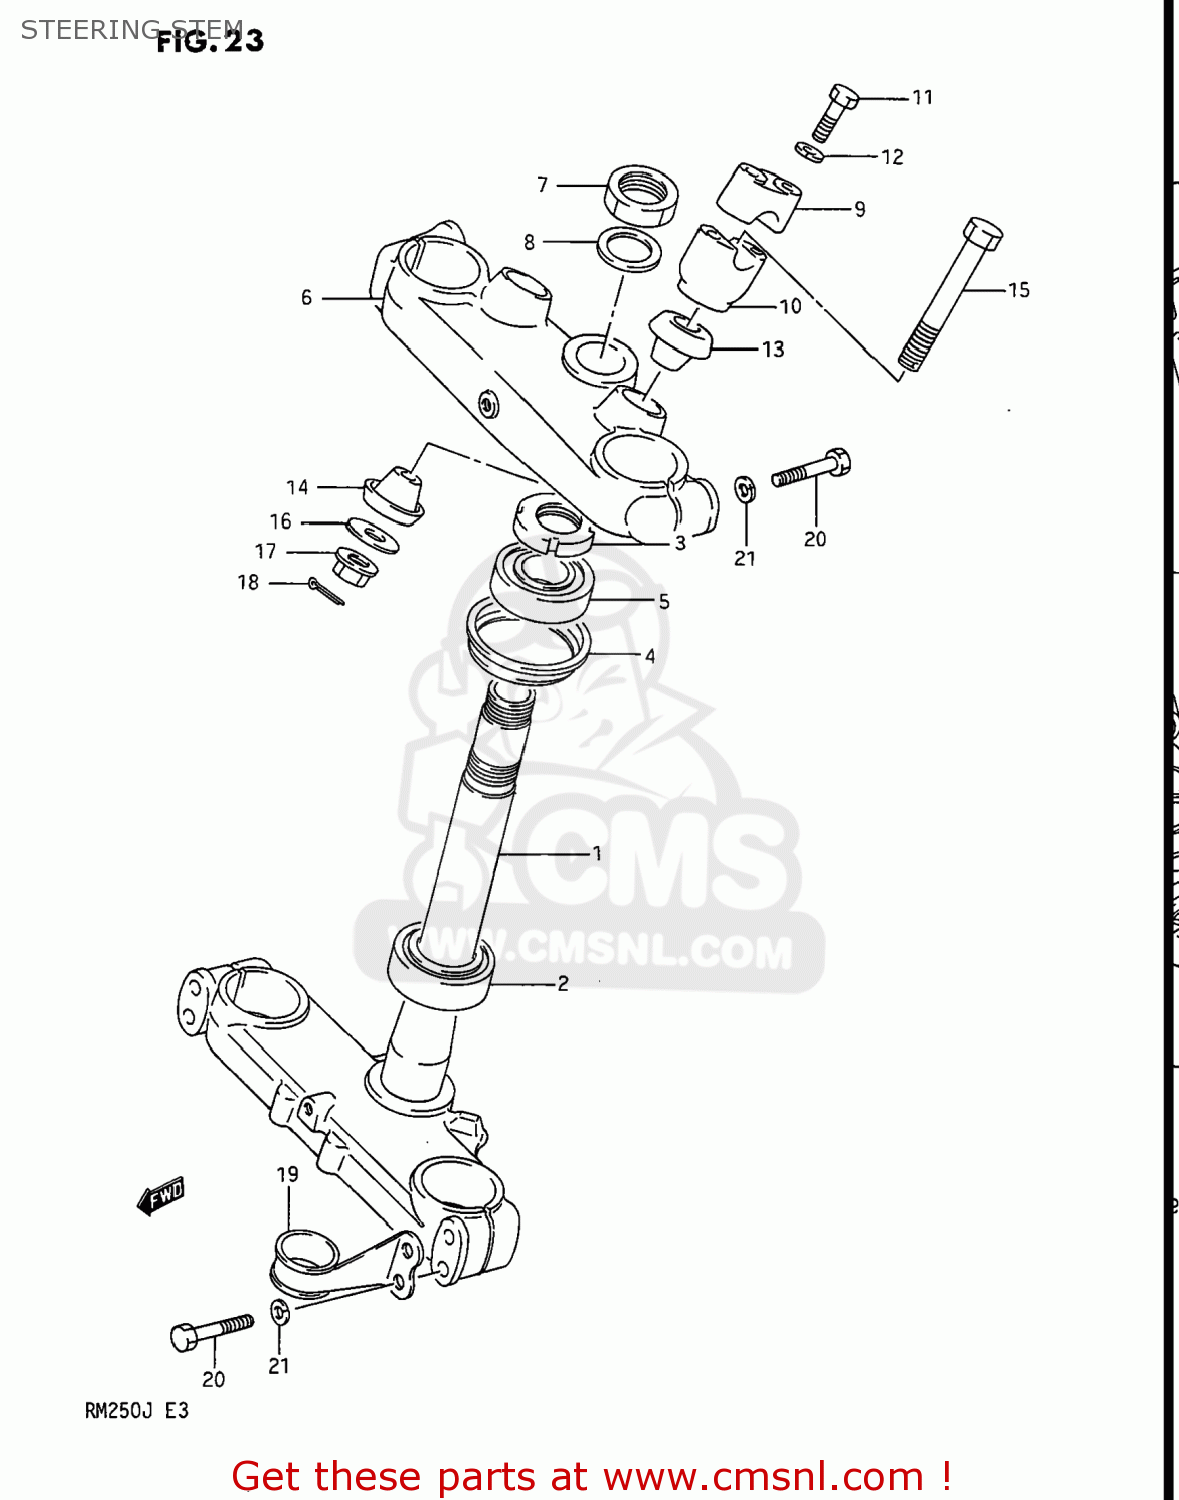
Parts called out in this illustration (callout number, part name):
1	STEM,STEERING
2	BEARING
3	NUT,STEERING STEM
4	SEAL,STEERING UPR DUST
5	TAPER,ROLLER BEARING
6	STEM HEAD,STEERING
7	NUT,STEERING STEM
8	WASHER
9	HOLDER,HANDLEBAR
10	HOLDER,HANDLE LWR
11	BOLT
12	WASHER,LOCK
13	DAMPER,UPR
14	DAMPER,LWR
15	BOLT,HANDLE HOLDER
16	WASHER,HANDLEBAR HOLDER
17	NUT
18	COTTER PIN
19	CLIP
20	BOLT 8X40
21	WASHER,LOCK
